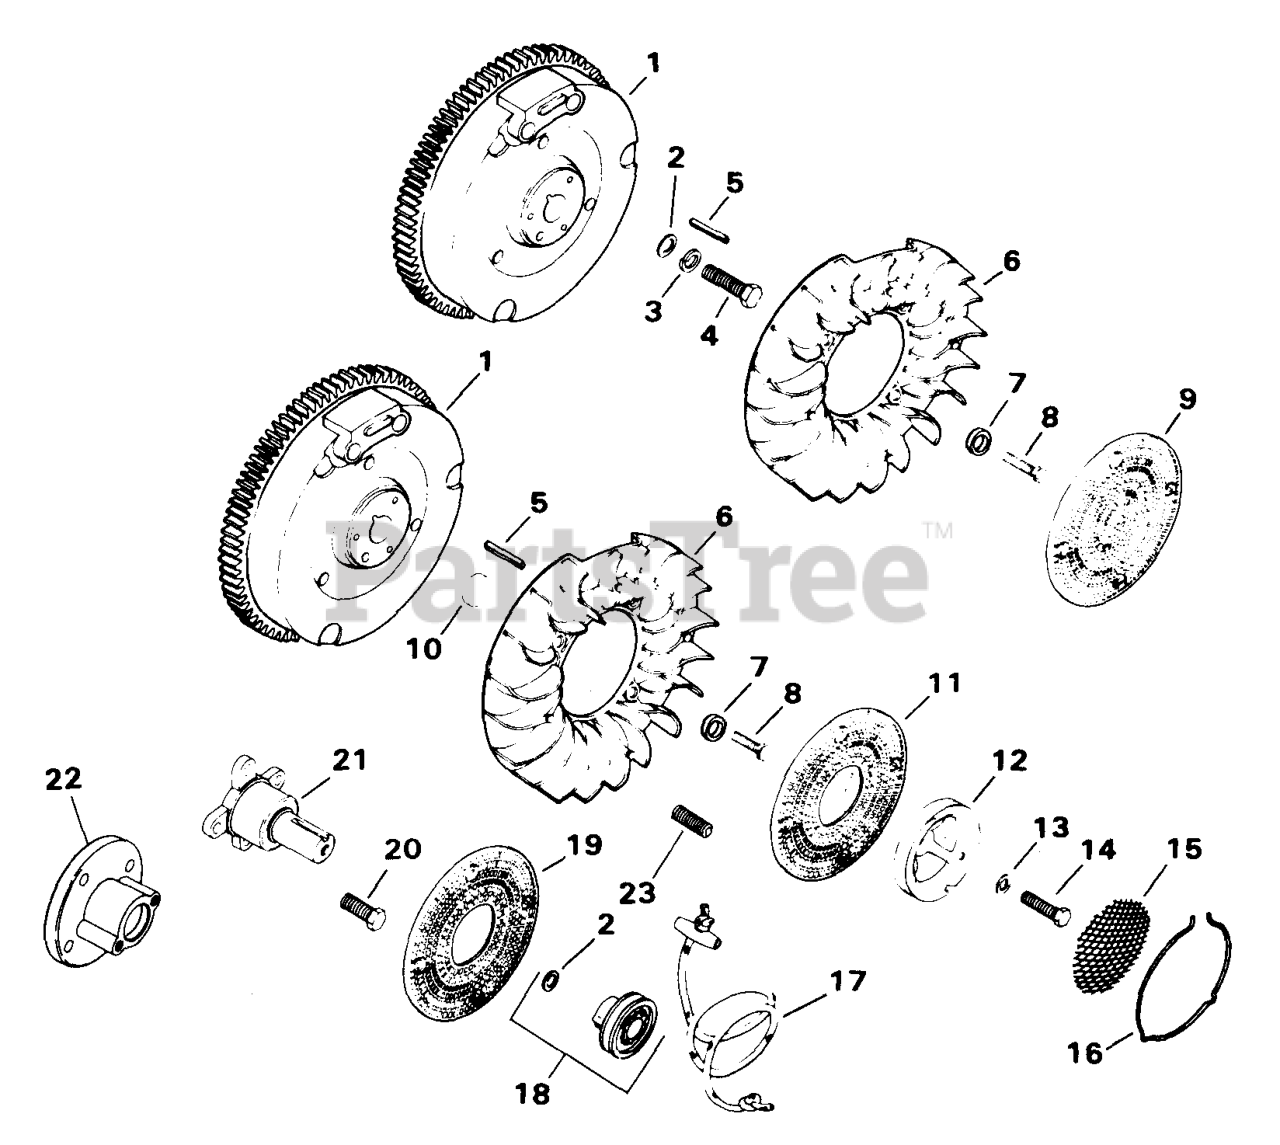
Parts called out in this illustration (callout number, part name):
1	FLYWHEEL - DISCONTINUED
2	WASHER (KM)-USE 12 468 03-S
4	SCREW, MACH 3/8-24X1-1/4"
8	SCREW, WSH HD 1/4-20X5/8" - DISCONTINUED
9	SCREEN, GRASS
